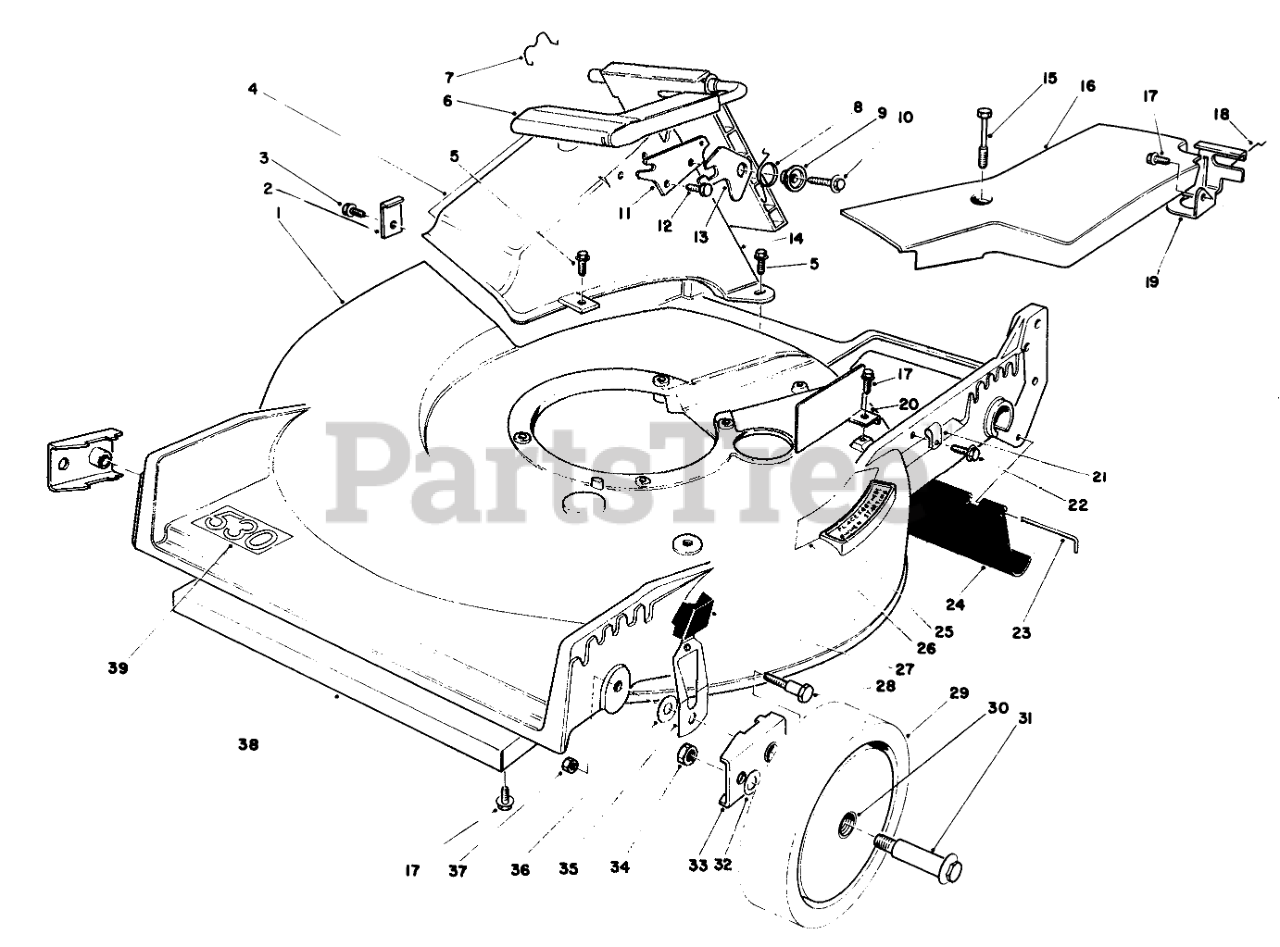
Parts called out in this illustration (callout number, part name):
1	21 SP RB HSG/DECAL
2	TUNNEL CLIP
3	SCREW
4	ATTENTION DECAL
5	SCREW-HWH
6	Discharge Door Assembly
7	DOOR RET SPRING
8	TORSION SPRING
9	DOOR SPACER
10	SCREW-HWH
11	DOOR LATCH PLATE
12	SCREW-PLASTITE
13	SAFETY LATCH
14	Tunnel Discharge
15	SCREW-HHFTF
16	Cover-Belt
17	SCREW-HWHTF
18	RETAINER-CABLE
19	Bracket-Traction Adj.
20	Shield-Muffler
21	CLAMP-CABLE
22	SCREW
23	ROD-SHIELD
24	SHIELD-TRAILING
25	STEP PAD DECAL
26	Decal-Place Foot Here
27	KNOB-ARM
28	PIVOT SCREW
29	Wheel & Tire Assy. (Incl. Ref. #30)
30	BUSHING
31	WHEEL BOLT
32	WASHER
33	HP PIVOT ARM ASM
34	NUT-LOCK
35	Spring Arm
36	WASHER-PIVOT
37	NUT-LOCK, NI
38	Shield-front
39	Decal-530
